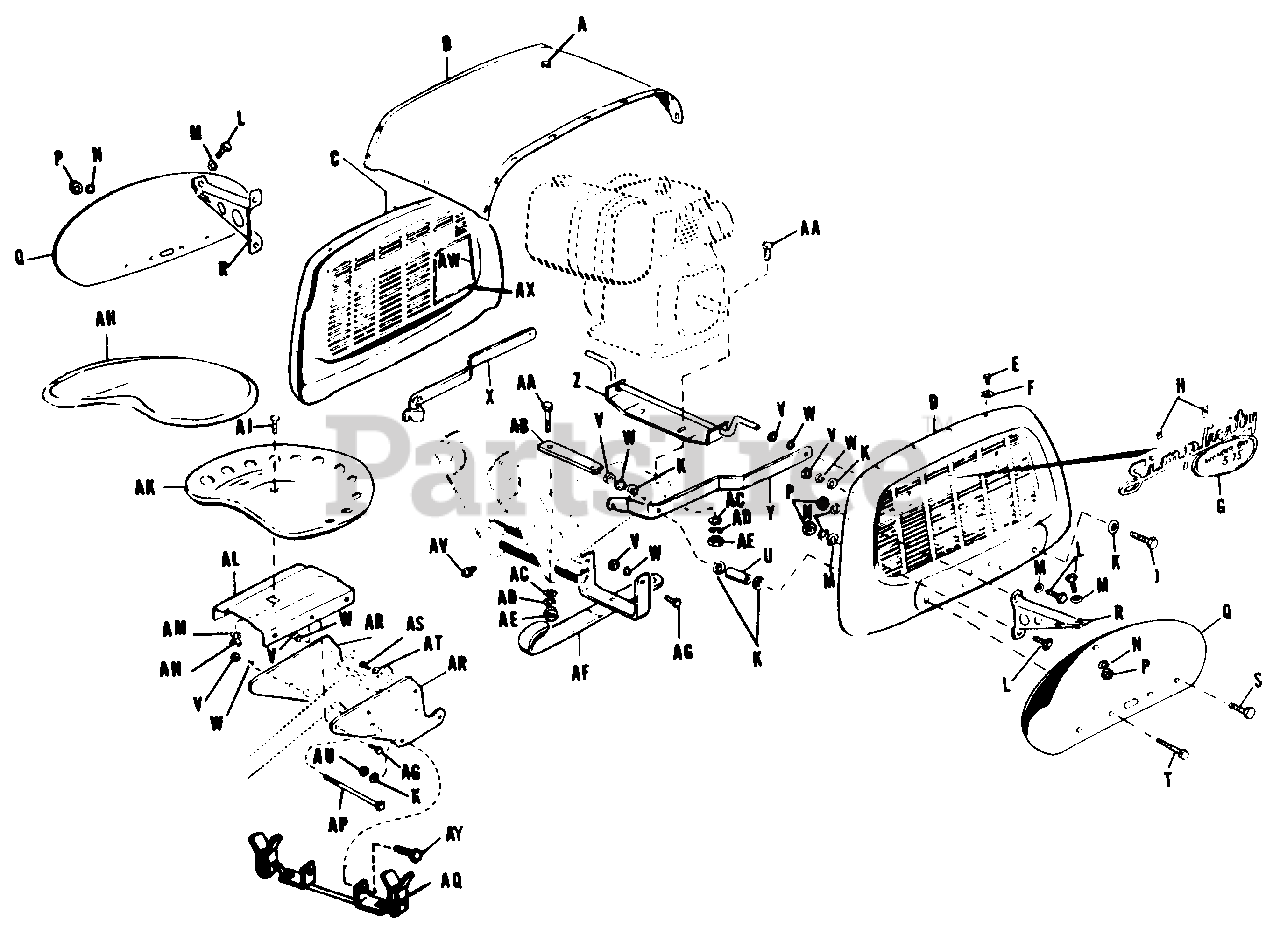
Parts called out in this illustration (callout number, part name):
A	Plug Button
B	Panel, Top
C	Panel, Side, R.H.
D	Panel, Side, L.H.
E	Screw, = 10 x 1/2
F	Speed Nut
G	Emblem, Simplicity Wonder-Boy "575"
H	Nut, Push-On
J	Capscrew, Hex Hd., 3/8-16 x 1 1/4
K	Washer, Lock
L	Capscrew, Hex Hd., 1/4-20 x 1/2
M	Washer, Plain, 1/4
N	Lockwasher, 1/4
P	Nut, Full Hex, 1/4-20
R	Brace, Fender
S	Capscrew, Hex Hd., 3/8-16 x 5/8
T	Capscrew, Hex Hd., 3/8-16 x 2
U	Spacer, Latch
V	Nut, Full Hex, 3/8-16
W	Washer, Lock, 3/8
X	Latch Arm, R.H.
Y	Latch Arm, L.H.
Z	Bracket Assembly, Pivot
AA	Capscrew, Hex Hd., 5/16-18 x 1 3/4"
AB	Spacer, Engine
AC	Washer, Plain, 5/16
AD	Washer, Lock, 5/16
AE	Nut, Full Hex, 5/16-18
AF	Draw Bar Assembly
AG	Capscrew, Hex Hd., 3/8-16 x 1
AH	Pad, Seat
AJ	Carriage Bolt, 1/2-13 x 1
AL	Support, Seat
AM	Washer, Lock, 1/2
AN	Nut, Full Hex, 1/2-13
AP	Bolt, Sq. Hd. Machine, 3/8-16 x 6
AQ	Catch Assembly
AR	Side Plate
AS	Capscrew, Hex Hd., 7/16-20 x 3/4
AT	Washer, Lock, 7/16 Internal Shakeproof
AU	Nut, Full Hex,
AV	Grease Fitting, Alemite #1637
AW	Trim, Side Panel
AX	Clip, for trim
AY	Cap Screw
